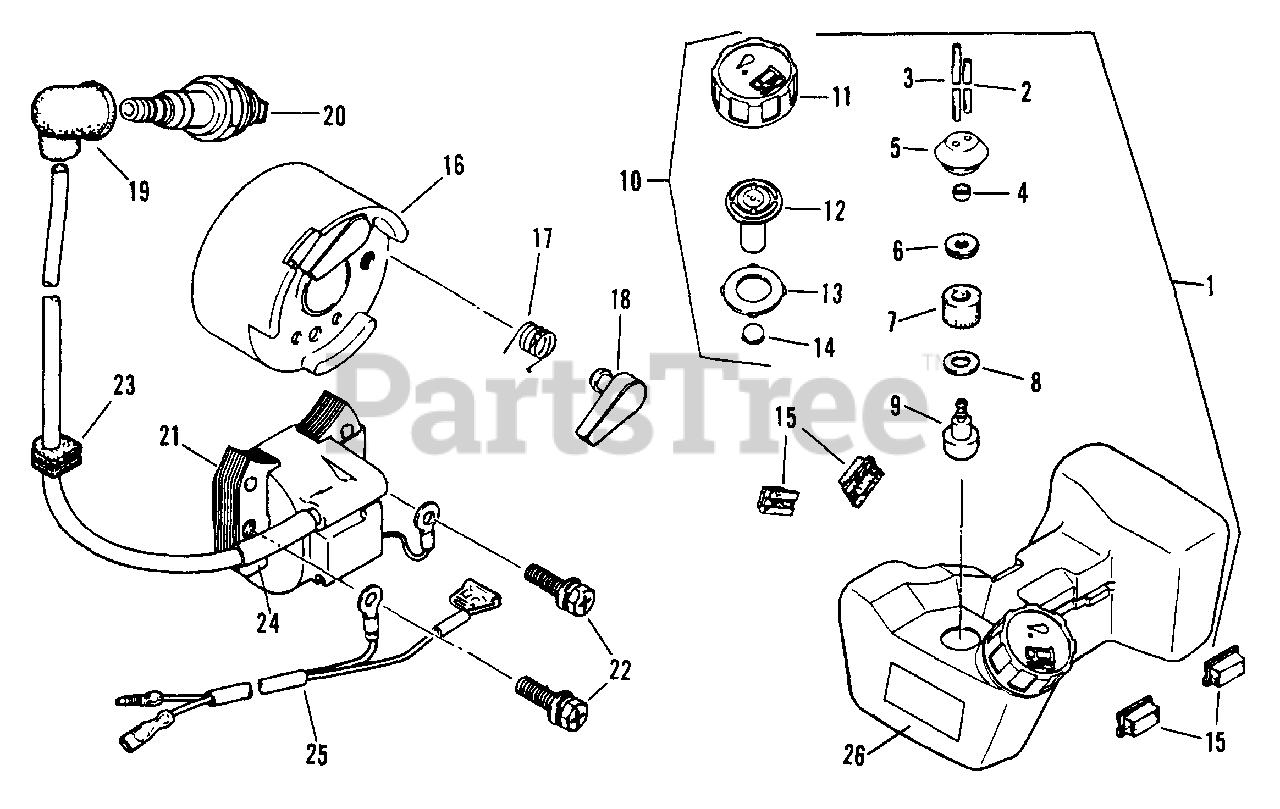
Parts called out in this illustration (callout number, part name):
1	ASSEMBLY, Fuel Tank
2	TUBE, Fuel
3	HOSE, Fuel
4	BUSHING
6	WASHER, Seal
7	FILTER, Fuel
8	SEAL, Dust
9	WEIGHT, Filter
10	ASSEMBLY, Tank Cap
11	CAP, Fuel Tank
12	VALVE, Breather
13	PACKING
16	ROTOR
17	SPRING, Return
18	RATCHET
19	CAP, Plug
21	COIL, Ignition
22	BOLT/WASHER
23	GROMMET
25	ASSEMBLY, Wire Lead
26	DECAL, Fuel Mix
